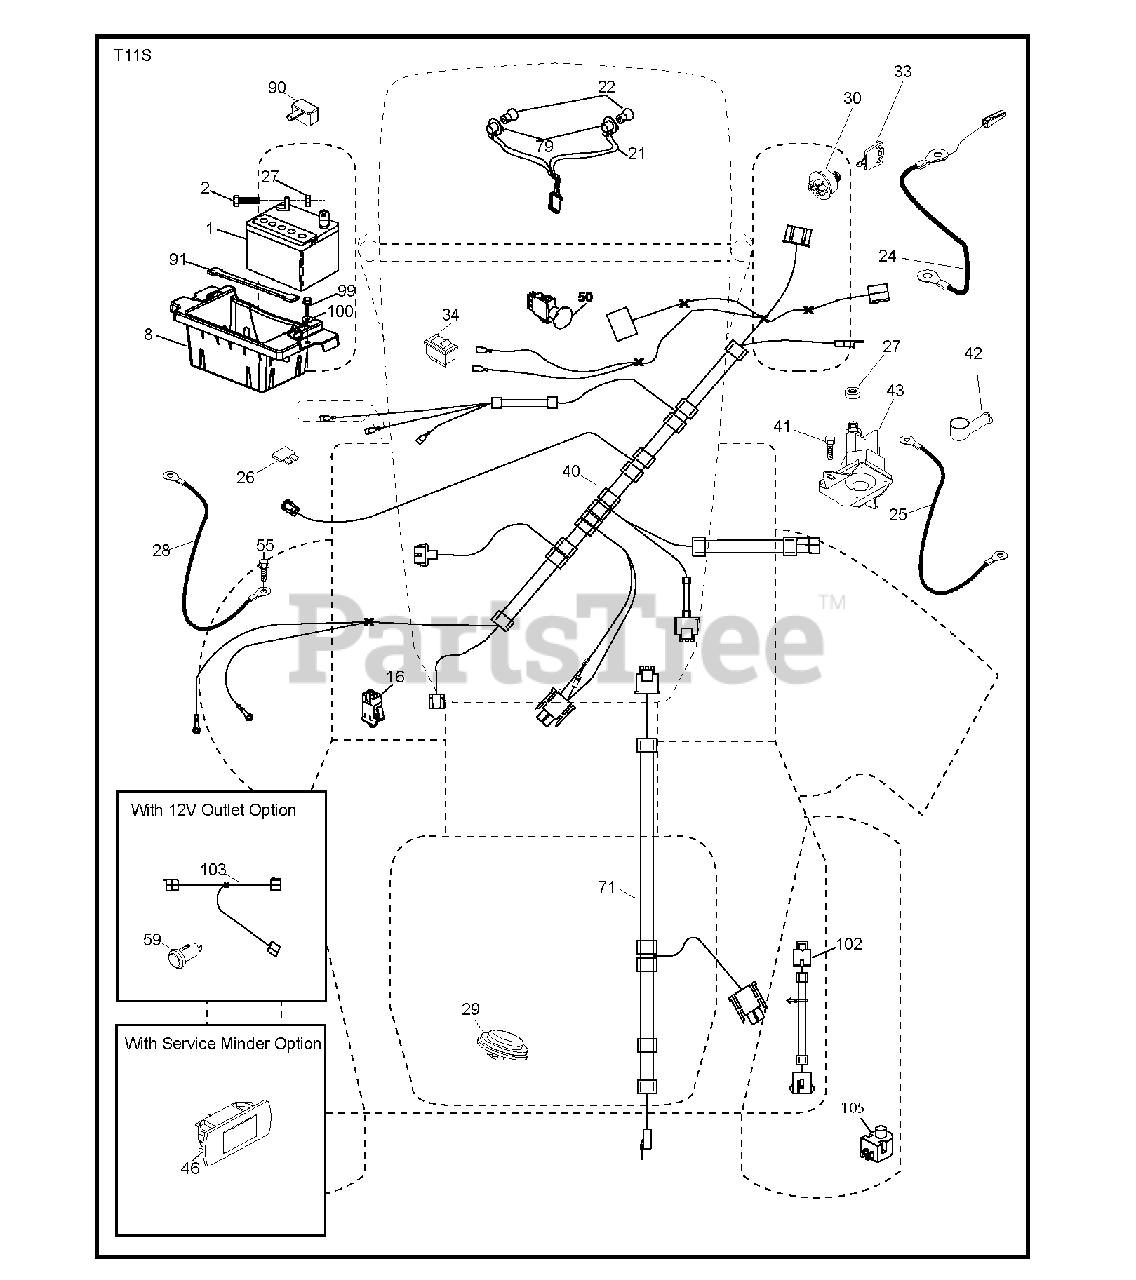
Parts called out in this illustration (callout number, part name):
1	Battery, Dry 30 Amp
2	BOLT.HEX.1/4.X.3/4.DICHROMATE
8	BOX.BATTERY.MOUNT.FRONT.LT
16	SWITCH INTERLOOK PUSH-IN
21	HARNESS ASSY LIGHT
24	CABLE.BATT.POS.WIRE.TG.DA SOL
25	CABLE.STARTER.6G.BL/RED.17.5
26	FUSE 20AMP
27	NUT
28	CABLE GROUND 6 GA 21" 90T BLK
29	SWITCH.SEAT.DELTA.OPC.
30	SWITCH.IGN.DELTA.W.LGH.ROS
33	KEY.CHAIN.BLISTER.PACK.GEN.USA
40	HARNESS.IGN.DASH.HUQ/P
41	SCREW
42	TERMINAL COVER
43	SOLENOID.W/BRASS.PLUNGER
46	RP GUAGE.SRVCMNDR.HRMTR.
50	RB PTO.SWITCH.8 TERMINAL.BLACK
55	SCREW 5/16"
71	HARNESS-CHASSIS SUB
79	BULB HOLDER ASM.
90	COVER.TERMINAL.BATTERY
91	STRAP.BATTERY.MOUNT.FRONT(2 2)
99	SCREW HEXWSHR 1/4-20X3/4
102	HARNESS PIGTAIL PCH TEX ROS
105	REVERSE SWITCH
